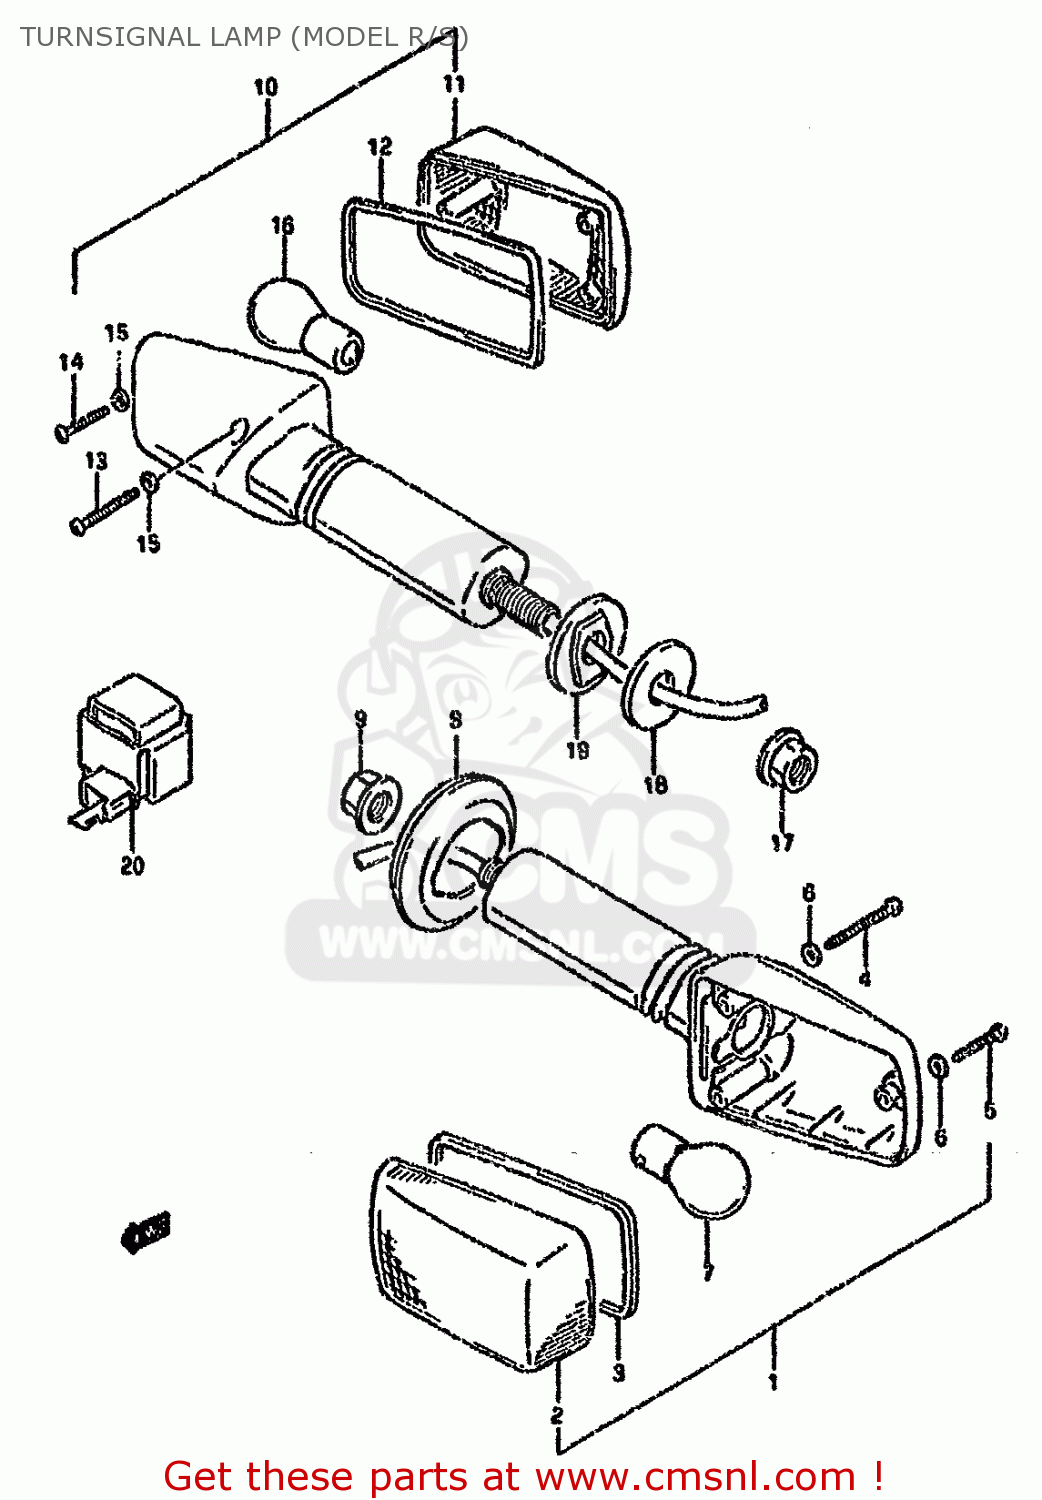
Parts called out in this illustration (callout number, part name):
1	LAMP ASSEMBLY,FRONT TURN SIGNAL
2	LENS
3	GASKET (NAS)
4	SCREW(3X30)
5	SCREW
6	GASKET (NAS)
7	BULB(12V21W)
8	GROMMET
9	NUT
10	LAMP ASSY,RR TURNSIGNAL
11	LENS
12	GASKET (NAS)
13	SCREW(3X30)
14	SCREW
15	GASKET (NAS)
16	BULB(12V21W)
17	NUT
18	WASHER(10.5X30X2.3)
19	SPACER,RR TURNSIGNAL
20	RELAY ASSY,TURNSIGNAL LAMP
21	LEAD WIRE,RELAY
